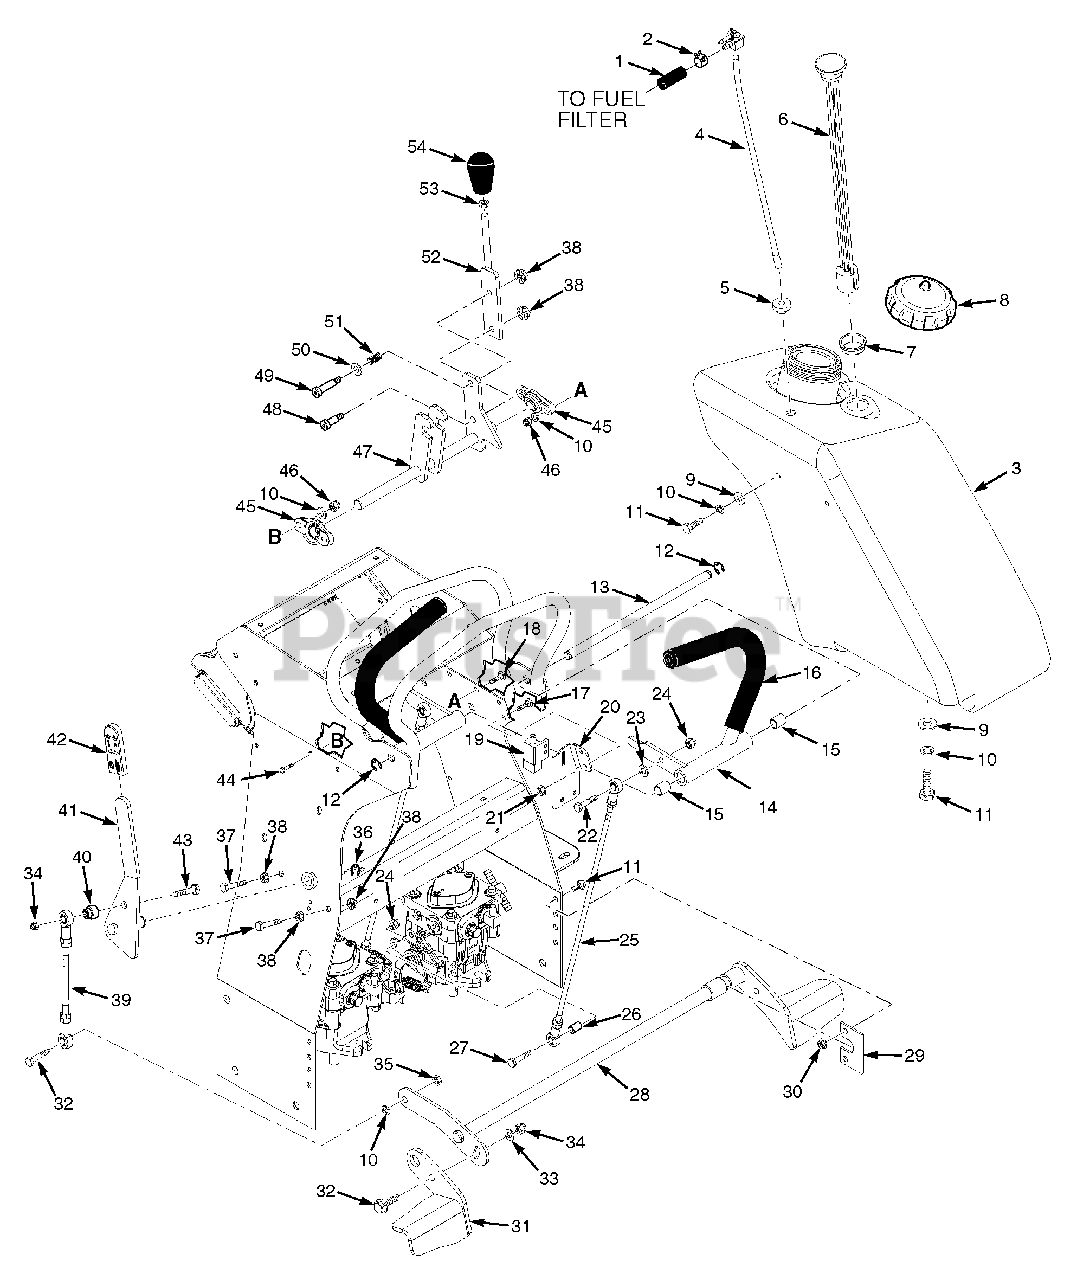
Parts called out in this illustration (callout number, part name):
1	Fuel Hose 1/4" ID
2	Clamp, Fuel Hose 1/4" ID
3	Fuel Tank Assy.
4	Valve, Fuel Shut Off
5	Bushing, .56 Viton
6	Fuel Gauge Assembly
7	Grommet, Fuel Gauge
8	Cap, Fuel Tank
9	Flatwasher, 5/16-.375 x .875 x .083
10	Lockwasher, 5/16" Spring
11	Bolt, Hex Heaf 5/16-18 x 3/4"
12	Retaining Ring, .50 External
13	Shaft, Steering Handles
14	Handle Bar Assy., LH
15	Bearing
16	Grip, Control Lever
17	Bolt, Carriage 1/4-20 x 3/4"
18	Bolt, Carriage 1/4-20 x 1"
19	Switch, Interlock
20	Bracket, Neutral Switch
21	Nut, Serrated Flange 1/4-20
22	Bolt, Hex Head 5/16-18 x 1-1/4"
23	Flatwasher, 5/16-.344 x .688 x .065
24	Nut, Elastic Stop 5/16-18
25	Linkage Assembly
26	Spacer, Pump
27	Bolt, Hex Head 5/16-18 x 1-3/4"
28	Bellcrank, Brake Weldment
29	Brake Keeper Plate
30	Nut, Serrated Flange 5/16-18
31	Brake Weldment, LH
32	Bolt, Hex Head 3/8-16 x 1-1/4"
33	Flatwasher, 3/8-.438 x 1.0 x .083
34	Nut, Elastic Stop 3/8-16
35	Nut, Center Lock 3/8-16
36	Retaining Ring, .625 External "E"
37	Bolt, Hex Head 5/16-18 x 1-1/2"
38	Nut, Serrated Flange 5/16-18
39	Linkage Assembly, Brake
40	Spacer
41	Brake Lever w/Grip
42	Grip, Brake Lever
43	Bolt, Hex Head 3/8-16 x 2"
44	Bolt, Hex Head 1/4-20 x 1"
45	Bearing
46	Nut, Elastic Stop 1/4-20
47	Lock Weldment, Neutral
48	Bolt, Shoulder 3/8 x .375
49	Bolt, Shoulder 3/8 x 1"
50	Flatwasher, 3/8-.406 x .812 x .065
51	Spring, Neutral Lever
52	Handle Weldment
53	Nut, Jam 3/8-16
54	Knob, Soft Touch
